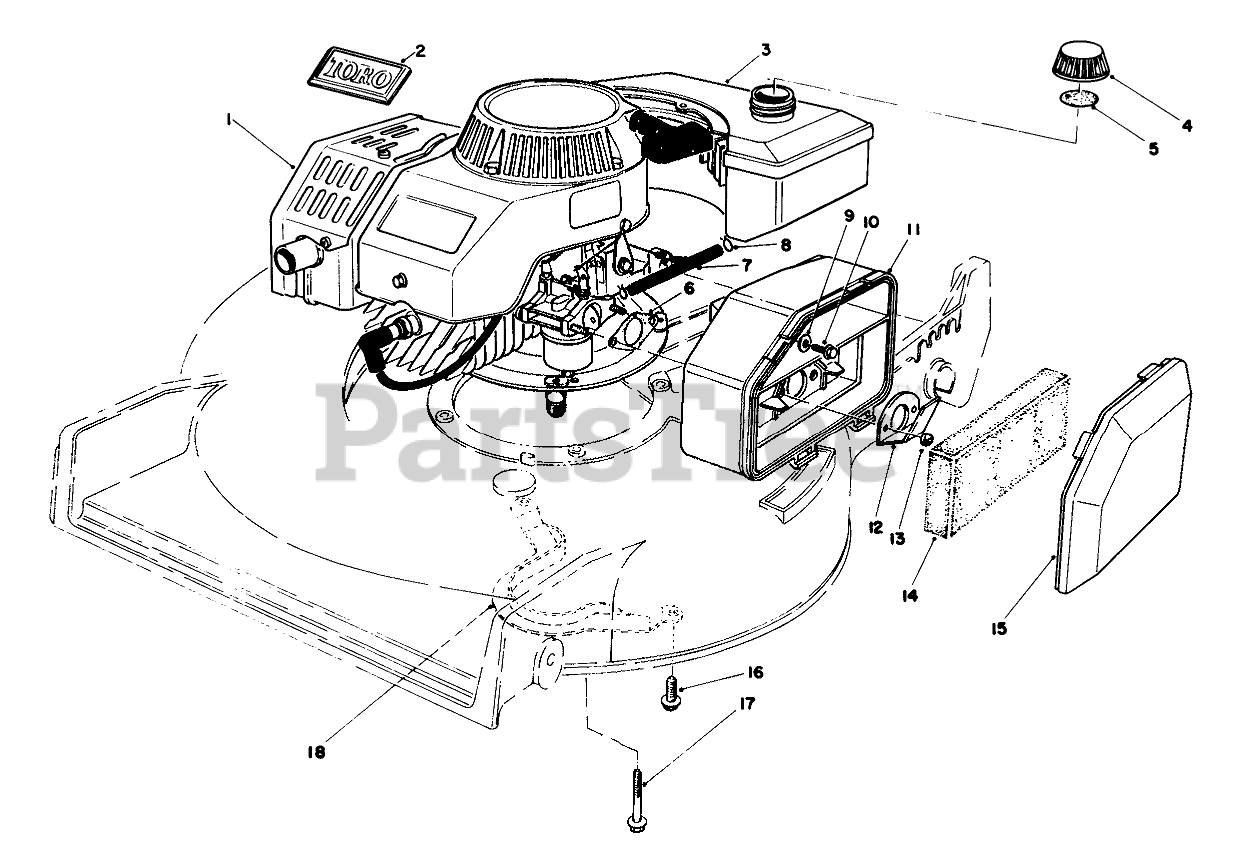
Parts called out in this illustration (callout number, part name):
1	Engine
2	TORO LOGO PLT
3	Gas Tank Assembly
4	Gas Cap Assembly (Incl. Ref. #5)
5	GAS CAP GASKET
6	GASKET-AIR CLEANER
7	FUEL LINE
8	CLAMP-HOSE
9	WASHER-FLAT
10	SCREW-HH
11	AIR CLEANER
12	SPIT BACK DEFLECTOR
13	NUT-LOCK
14	FILTER
15	AIR CLEANER COVER
16	Screw
17	SCREW-HHF
18	BELT GUIDE
